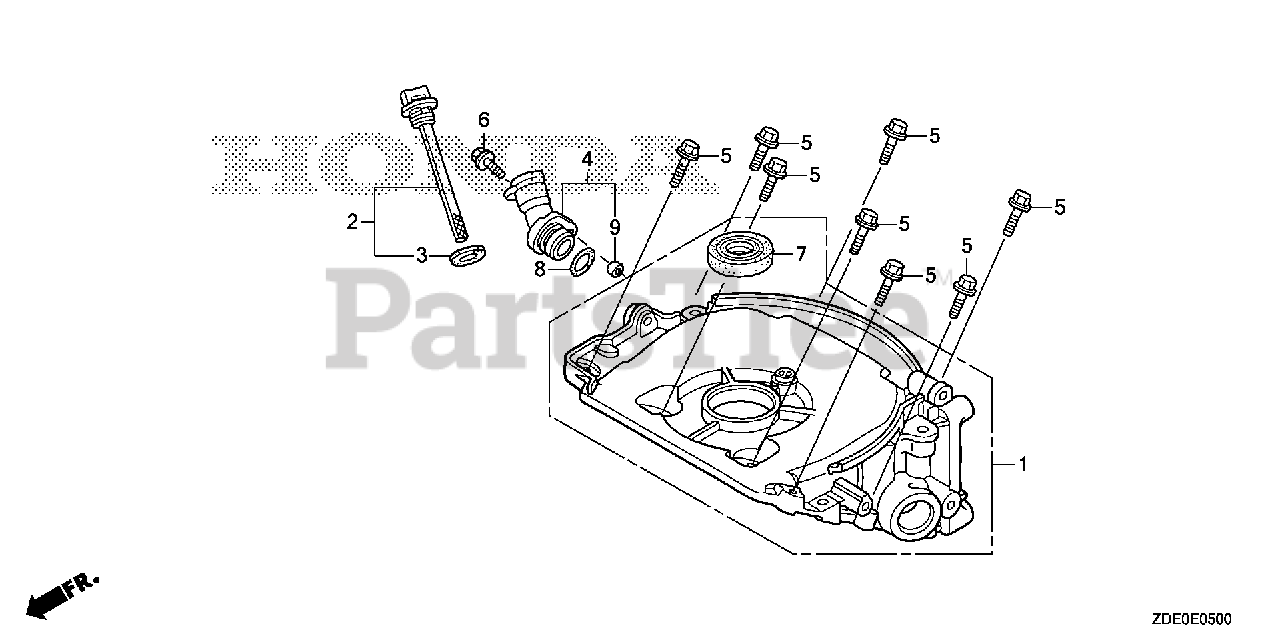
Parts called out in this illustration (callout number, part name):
1	CASE ASSY., OIL
2	CAP ASSY., OIL FILLER
3	GASKET, OIL FILLER CAP
4	EXTENSION, OIL FILLER
5	BOLT, FLANGE (5X23)
6	BOLT, FLANGE (5X14)
7	OIL SEAL (17X27X5) (KOYO)
8	O-RING (21.2X2.4) (ARAI)
9	COLLAR, TOP COVER
